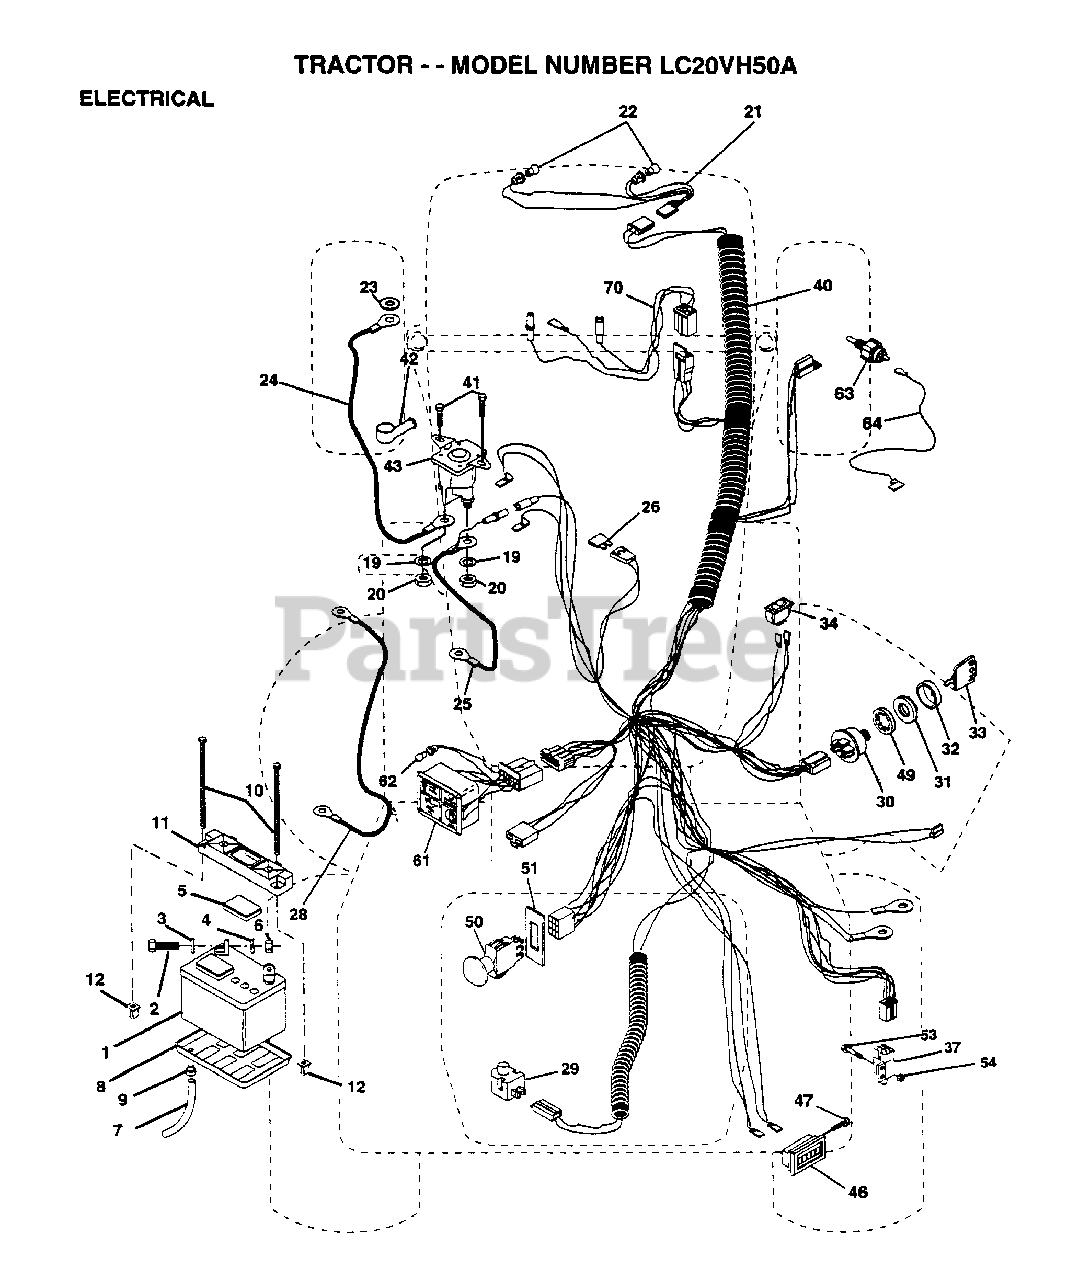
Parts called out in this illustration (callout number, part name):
2	BOLT LT
3	LOCKWASHER
4	WASHER
5	"CAP,BATTERY "
7	"DRAIN TU T, BATT"
8	"TRAY T, BATTERY"
9	HOSE CLAMP T
20	NUT
21	"HARNESS,LIGHT SOC"
22	HEADLAMP BULB
23	LOCKWASHER
24	"CABLE T, BATTERY"
25	CABLE-BATTERY T
26	FUSE HYT
28	CABLE T
29	SWITCH SEAT
32	COVER KEY SWITCH
33	KEY MLD GEN DELTA
34	SWITCH LT
37	SWITCH INTERLOCKT
40	HARNESS.IGN.GT.EL
41	SCREW
46	HOUR METER T
47	SCREW
49	LOCKWASHER
51	RING RETAIN PTO
53	SCREW
54	"NUT,KEPS"
61	LIGHT.PKG.ASM.
62	BULB LIGHT T
63	SWITCH OIL KOHLER
64	WIRE.LEAD.SENTRY
70	HARNESS.ENG.VANII
